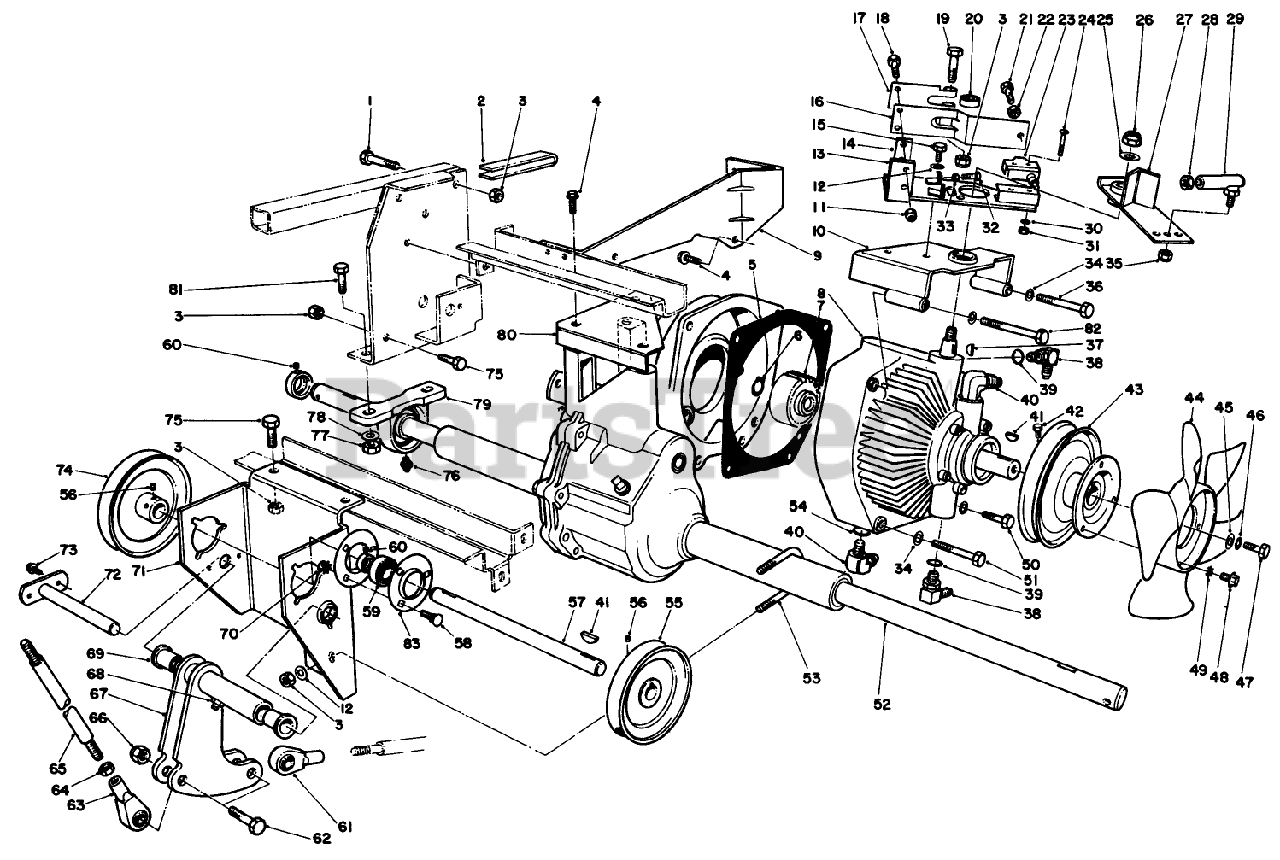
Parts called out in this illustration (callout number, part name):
1	SCREW-HH
2	TUBE SPACER
3	NUT-LOCK, NI
4	SCREW-HHF
5	TRANS GASKET
6	RING-SNAP, EXTERNAL
7	GEAR-SPUR
8	HYDROSTATIC TRANS.
9	Bracket-Transaxle
10	TR CONT BRKT WA B
11	NUT-LOCK, NI
12	WASHER-PLAIN
13	TRACT PLATE WA B
14	SHIM-ARM, SPRING
15	SCREW-HH
16	EXTENDED LEAF SPRING ASM
17	SPRING-LEAF
18	SCREW-HH
19	SCREW-HH
20	BEARING-BALL
21	SCREW-HH
22	NUT-JAM
23	SWITCH-MICRO
24	SCREW-MACHINE
25	WASHER-FLAT
26	NUT-LOCK, NI
27	TRACT LEVER WA B
28	NUT-JAM
29	JOINT-BALL
30	WASHER-LOCK, INTERNAL
31	NUT-HEX
32	SCREW-HH
33	NUT-JAM
34	WASHER-LOCK
35	NUT-LOCK
36	SCREW-HH
37	KEY-WOODRUFF
38	Fitting-Hydraulic 90deg. (Incl. Ref. #39)
39	O-RING
40	Fitting-Hydraulic 90deg. (Incl. Ref. #54)
41	KEY-WOODRUFF
42	SCREW-SQH
43	TRANS PULLEY
44	FAN 8"
45	WASHER-FLAT
46	WASHER-LOCK
47	SCREW-HH
48	SCREW-SHWH
49	WASHER-LOCK/EXT
50	SCREW-HH
51	SCREW-HH
52	Differential Assembly
53	U-BOLT
54	O-RING
55	JACKSHAFT INPUT PULLEY
56	SCREW-SET, SQH
57	JACKSHAFT
58	BOLT-CARR
59	BEARING-BALL
60	SCREW-SET, HSH
61	BALL JOINT LH
62	SCREW-HH
63	BALL JOINT RH
64	NUT-JAM
65	Rod-Steering
66	NUT-HEX
67	Bellcrank Assembly (Incl. Ref. #68 & 69)
68	GREASE FITTING
69	BUSHING PM
70	NUT-KEPS
71	Bracket-Jackshaft
72	Shaft-Bellcrank
73	SCREW-HHFTF
74	JACKSHAFT OUTPUT PULLEY
75	SCREW-HH
76	FITTING-GREASE
77	Nut-Lock
78	WASHER-FLAT
79	BEARING - PILLOW BLOCK
80	TRANSAXLE PLATE
81	SCREW-HH
82	SCREW-HH
83	FLANGE
